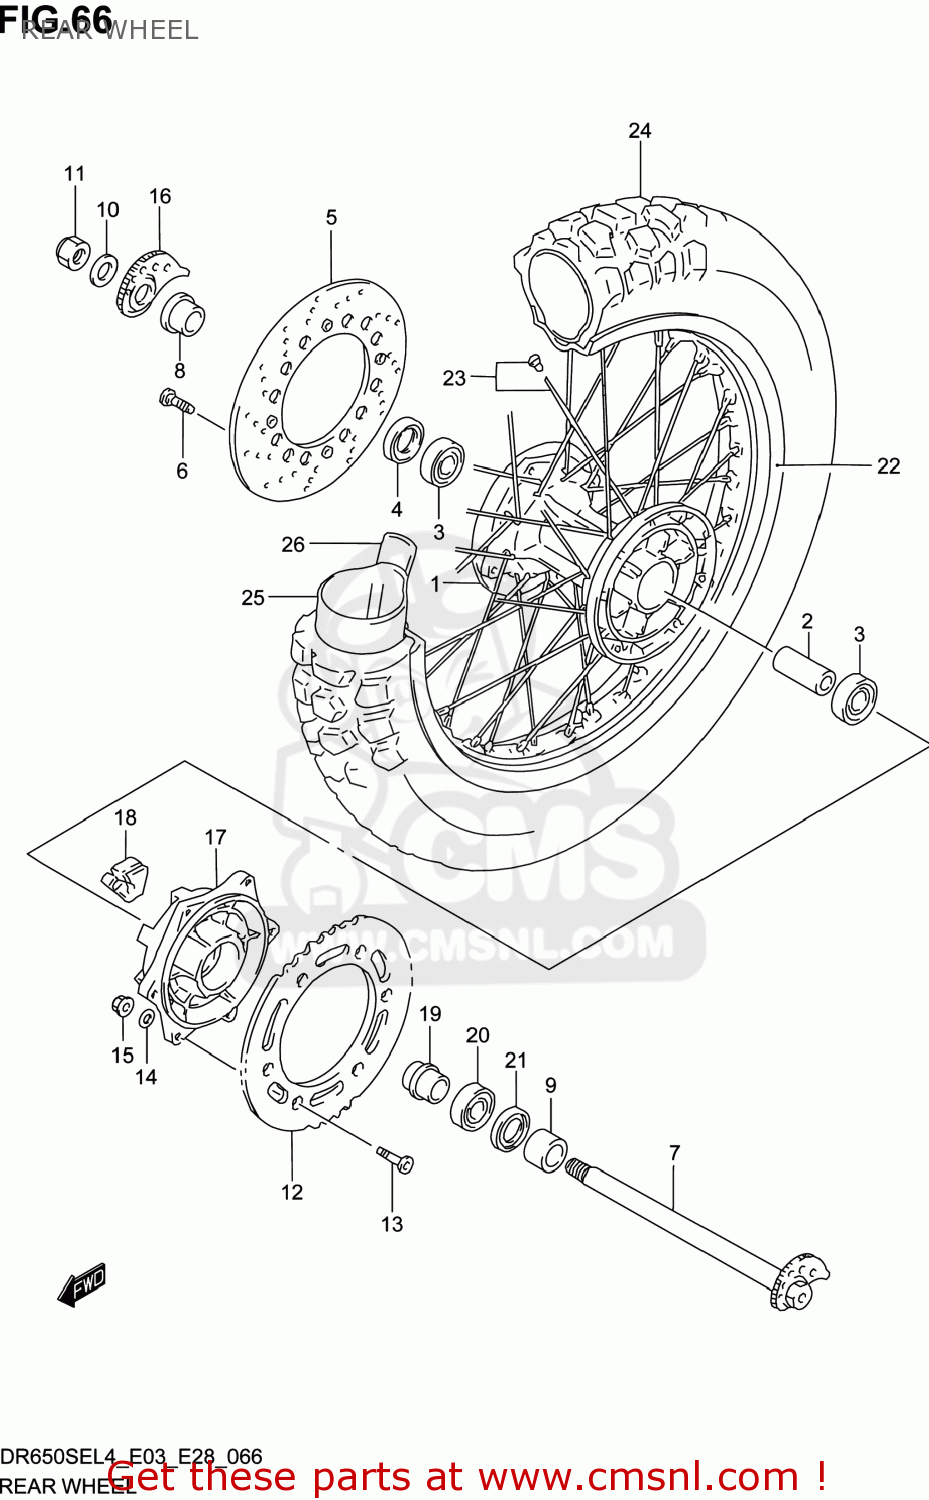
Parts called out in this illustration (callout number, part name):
1	HUB,RR WHEEL
2	SPACER,RR HUB BEARING
3	BEARING
4	SEAL,OIL(26X47X5)
5	DISC,RR BRAKE
6	BOLT(8X20)
7	AXLE,RR
8	SPACER,RR AXLE,R
9	SPACER,RR AXLE,L
10	WASHER(19X32X3.2)
11	NUT
12	SPROCKET,RR(NT:42)
13	BOLT(8X30.5)
14	WASHER
15	NUT
16	ADJUSTER,CHAIN,R
17	DRUM,RR SPROCKET MOUNTING
18	ABSORBER,RR HUB SHOCK
19	RETAINER,RR SPROCKET DRUM
20	BEARING(25X52X15)
21	SEAL,OIL(34X52X6)
22	RIM,RR WHEEL(17M/CXMT2.50)
23	SPOKE SET,RR WHEEL
24	TIRE,RR(120/90-17 64S)
25	TUBE ASSY,WHEEL INNER
26	PROTECTOR,WHL INR TUBE
